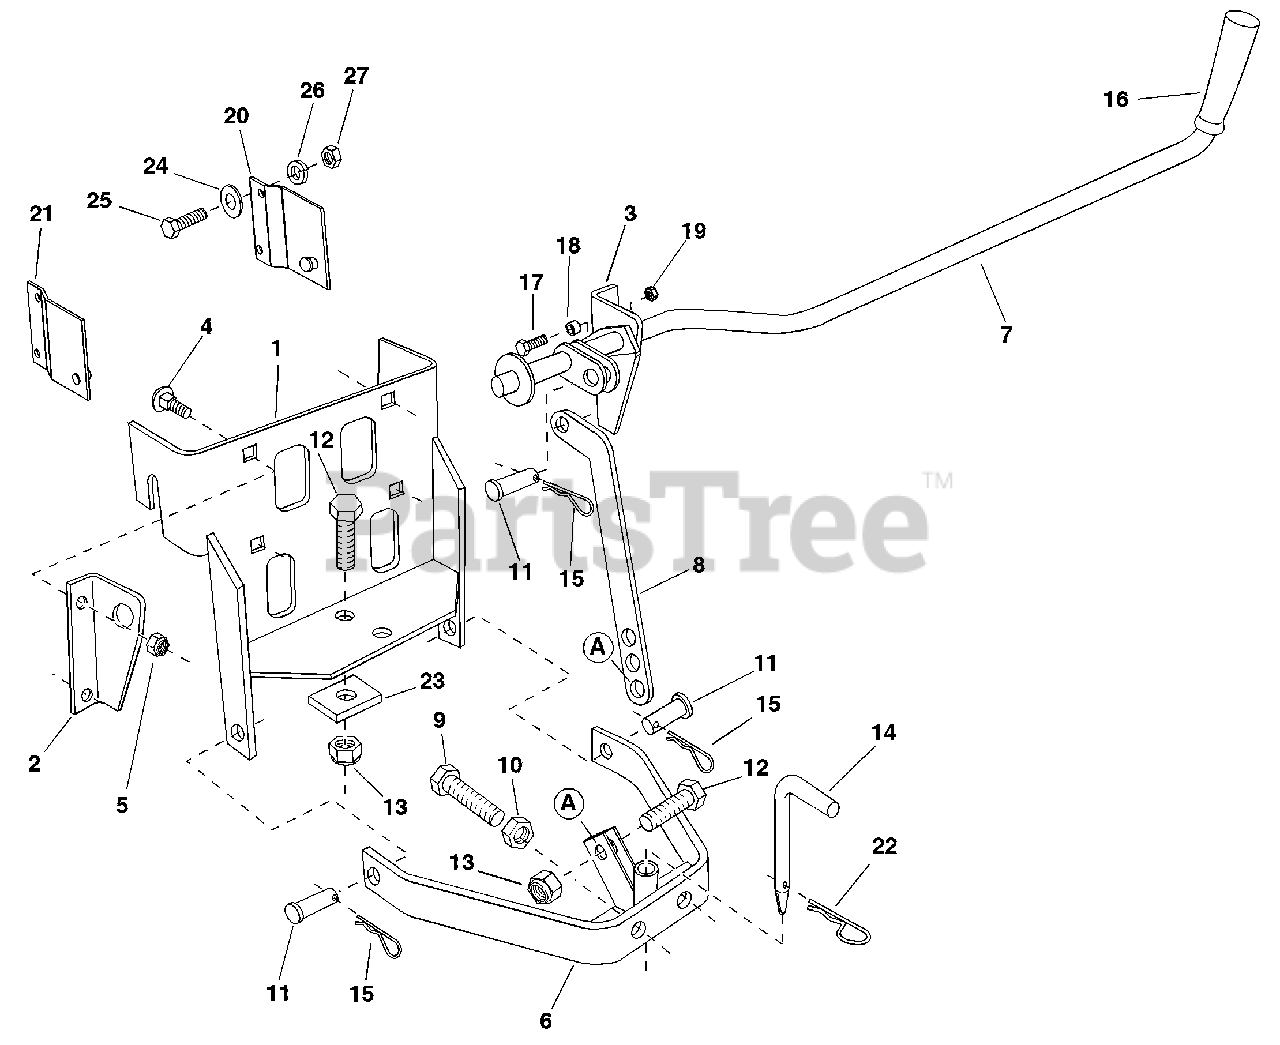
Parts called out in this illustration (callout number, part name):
1	Sleeve Hitch Frame
2	Pivot Bracket, Left
3	Pivot Bracket, Right
4	Bolt, Carriage 3/8-16 x 1"
5	Hex Lock Nut, 3/8-16
6	Sleeve Hitch Lift Assembly
7	Lift Lever Assembly
8	Lifting Link Plate
9	Bolt, Hex 5/8-11 x 2"
10	Hex Jam Nut, 5/8-11
11	Clevis Pin, 5/8" x 1-3/4"
12	Bolt, Hex 5/8-11 x 1-3/4"
13	Nylock Nut, 5/8-11
14	Pin, Sleeve Hitch
15	Pin, Hair Cotter 3/32"
16	Grip, Plastic
17	Bolt, 5/16-18 x 1"
19	Nylock Nut, 5/16"
20	Mounting Bracket, Right
21	Mounting Bracket, Left
22	Pin, Hair Cotter, 5/32"
23	Spacer Plate
24	Flat Washer
25	Bolt, Hex 3/8-16 x 1-1/4"
26	Lock Washer, 3/8"
27	Hex Nut, 3/8-16
